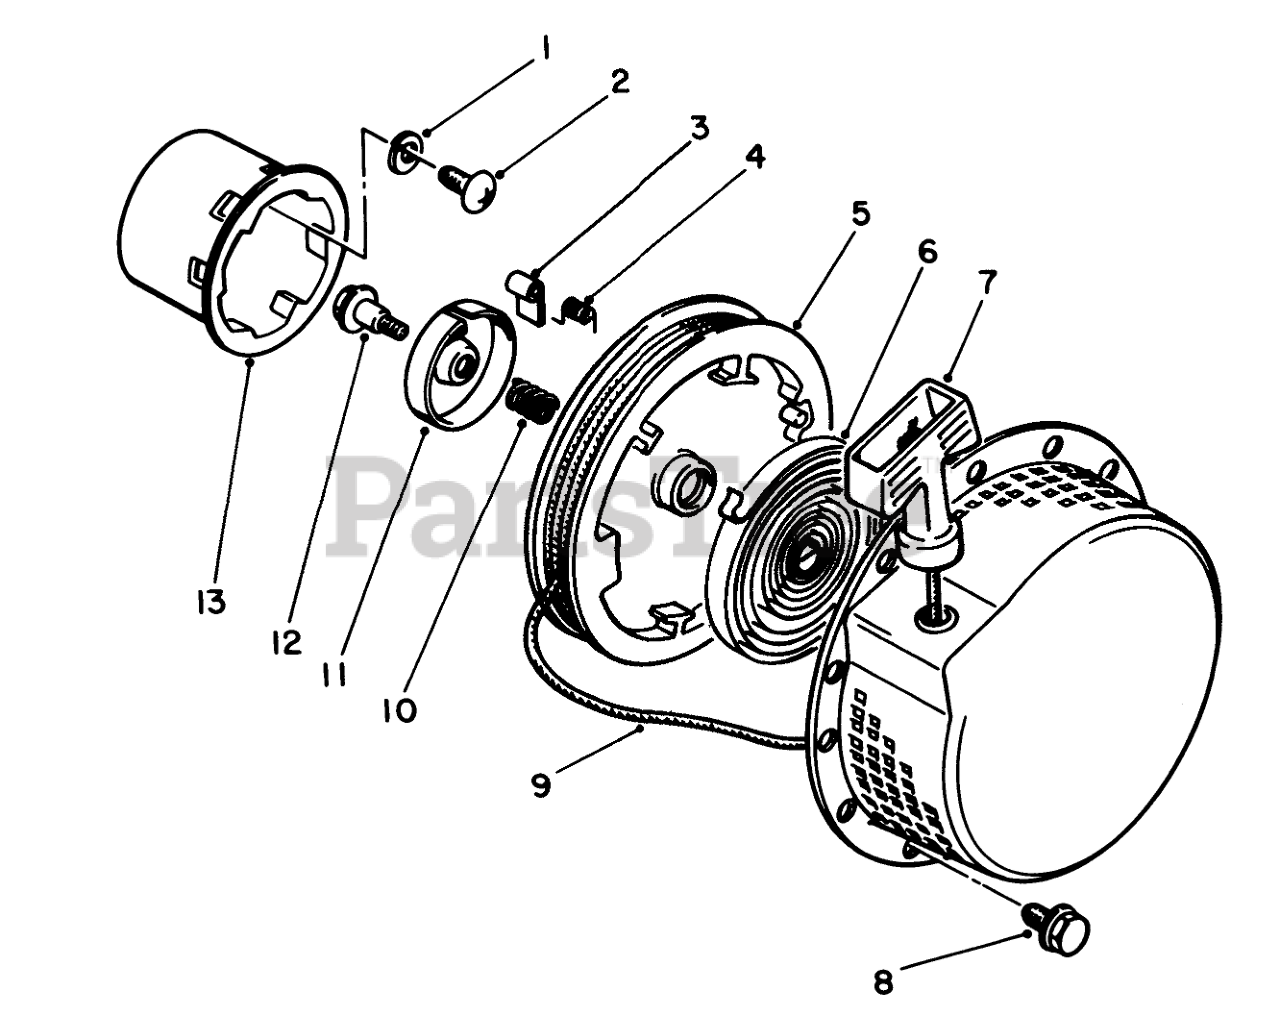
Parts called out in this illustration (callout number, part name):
1	Washer-Lock
2	Screw
4	SPRING
6	SPRING
7	Grip-Hand
9	Starter Rope Assembly (Incl. Ref. #7)
10	SPRING
11	RETAINER
13	Pulley
